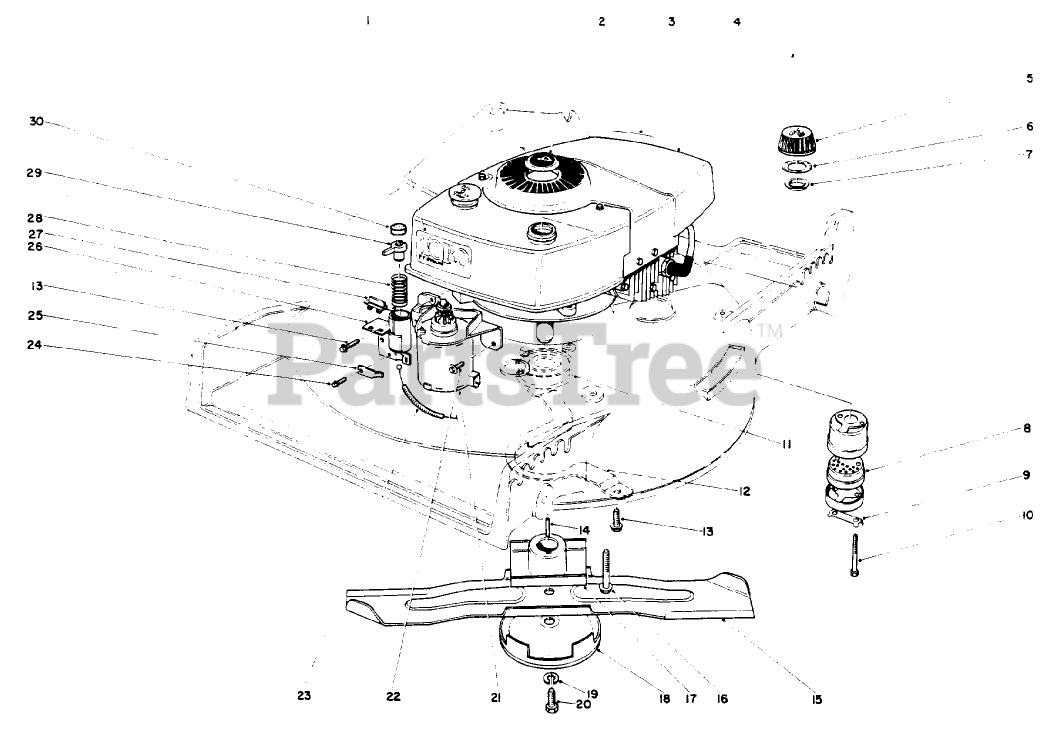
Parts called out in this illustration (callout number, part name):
1	Decal
2	PLUG BUTTON
3	Decal-Maintenan
4	Engine
5	Gas Cap Assembly (Incl. Ref. #6 & 7)
6	GASKET
7	GAS CAP BAFFLE
8	Muffler Assembly (Incl. Ref. #9 & 10)
9	CLIP - LOCKING
10	SCREW-HH
11	Engine Pulley
12	BELT GUIDE
13	Screw
14	KEY-SQUARE
15	Blade
16	Hex Washer Hd. Tapping Screw
17	BLADE RETAINER WA(BLACK)
18	AntiScalp Cup
19	WASHER-LOCK
20	BLADE SCREW
21	Starter Motor Assembly
22	SCREW
23	Brake Cable
24	SCREW
25	Cable Clamp
26	Tube Assembly
27	Switch
28	Spring
29	Plunger
30	Pad-Friction
